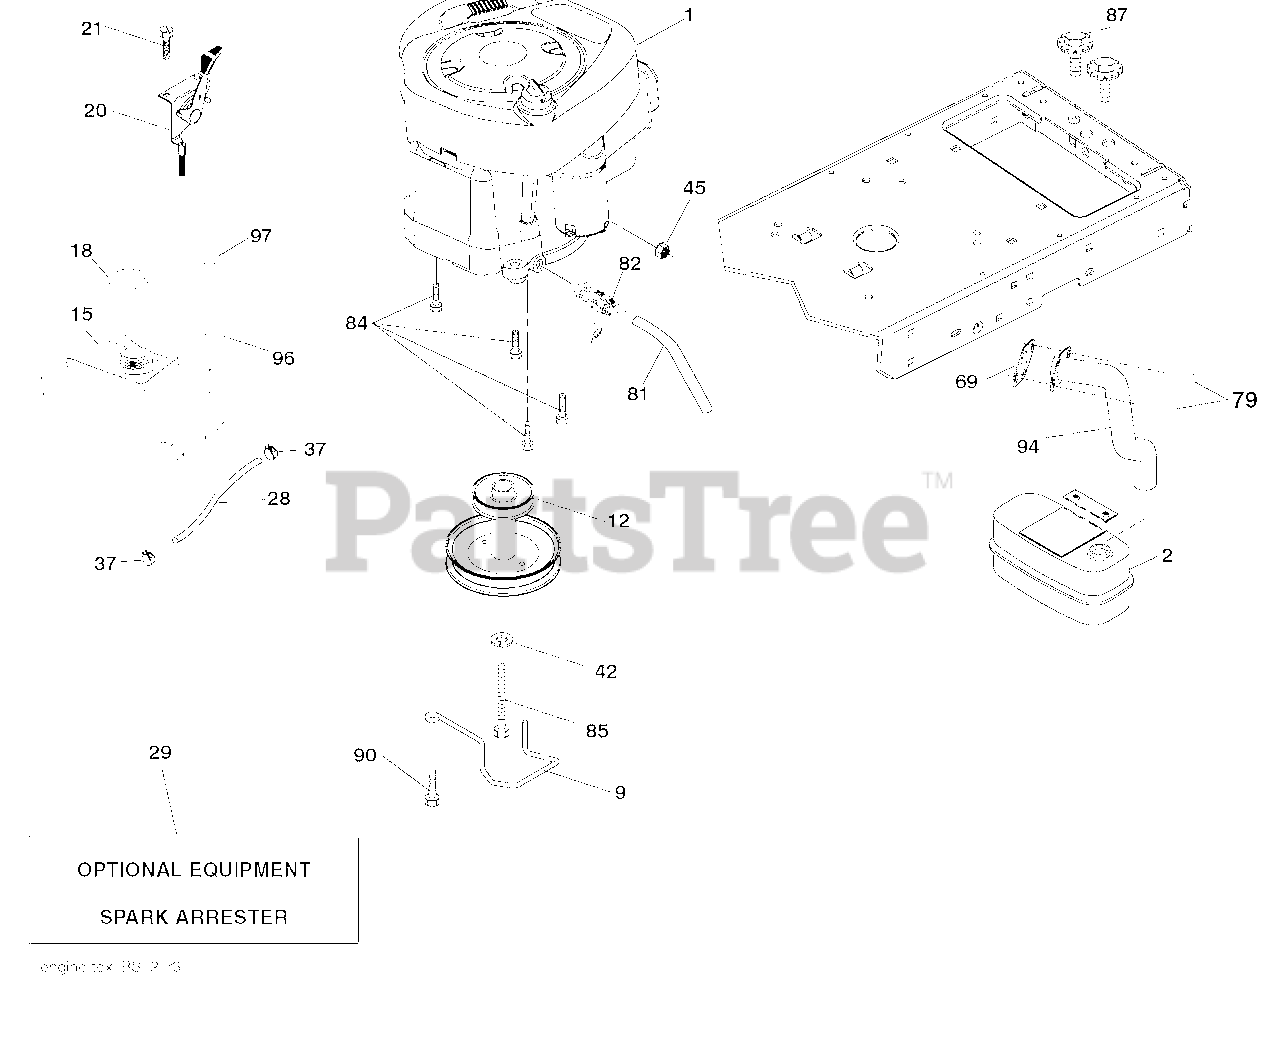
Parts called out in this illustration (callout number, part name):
9	Keeper Belt Engine
12	Pulley Engine
15	Tank Fuel
18	Cap Asm
20	Control Throttle
21	Screw #10 x 0.750 BOS Thread
28	Fuel Line
29	Spark Arrester Kit
37	Clamp Hose
42	Washer Lock 7/16
45	Nut Keps Hex 1/4-20 unc
69	Gasket
79	Screw 5/16-18 x 3/4
81	Tube Drain Oil Easy
82	Valve Drain Oil
84	Screw 3/8-16 x 1/4
85	Bolt Hex 7/16-20 x 4 Gr. 5
87	Bolt 5/16-18 unc x 3/4 w/sems
90	Screw 3/8-16 x 1
94	Exhaust Tube
96	Washer 9/32 x 7/8 x 16 Ga.
97	Screw 1/4-20 x 3/4
